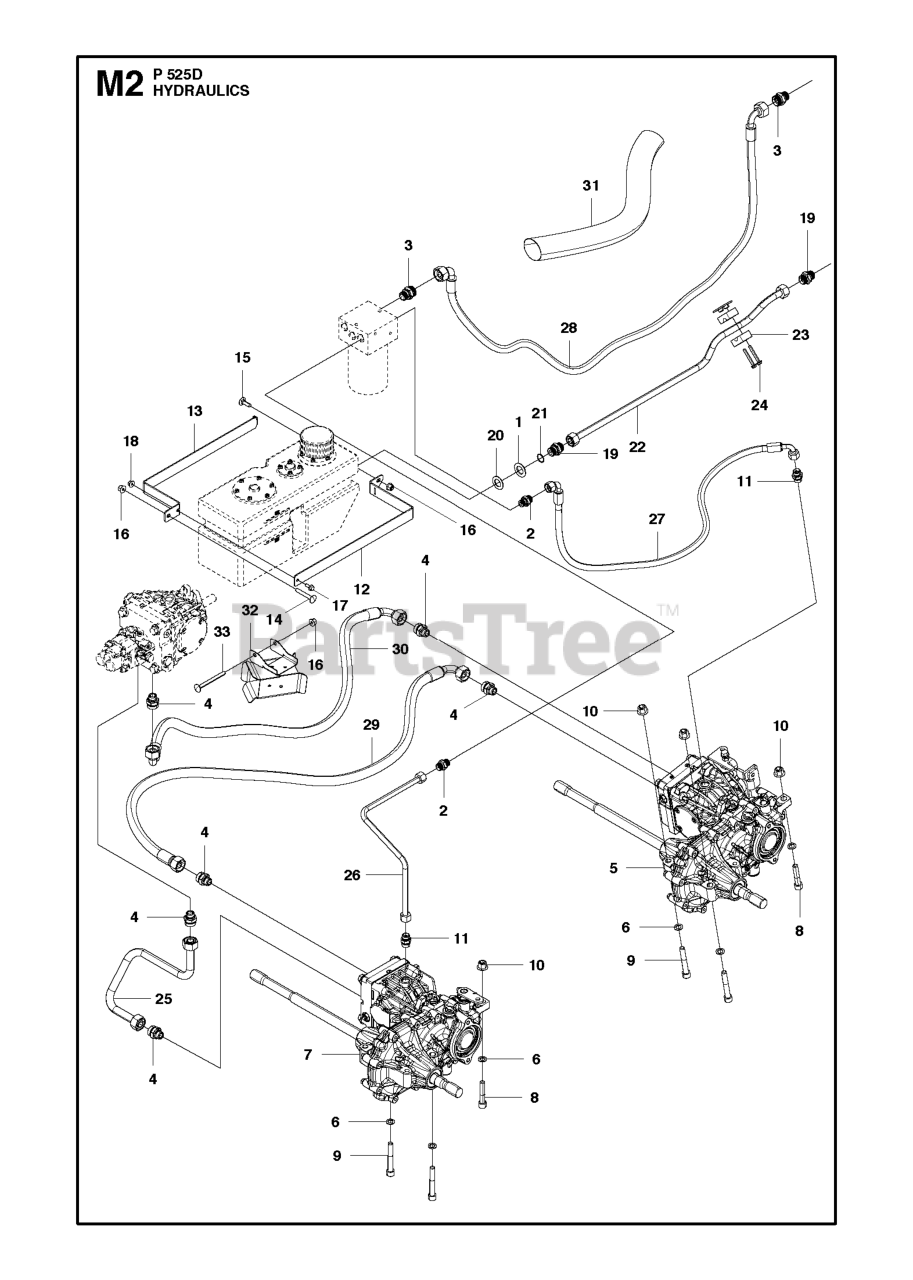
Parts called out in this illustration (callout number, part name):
16	NUT FLANGE
17	Screw
18	NUT FLANGE
